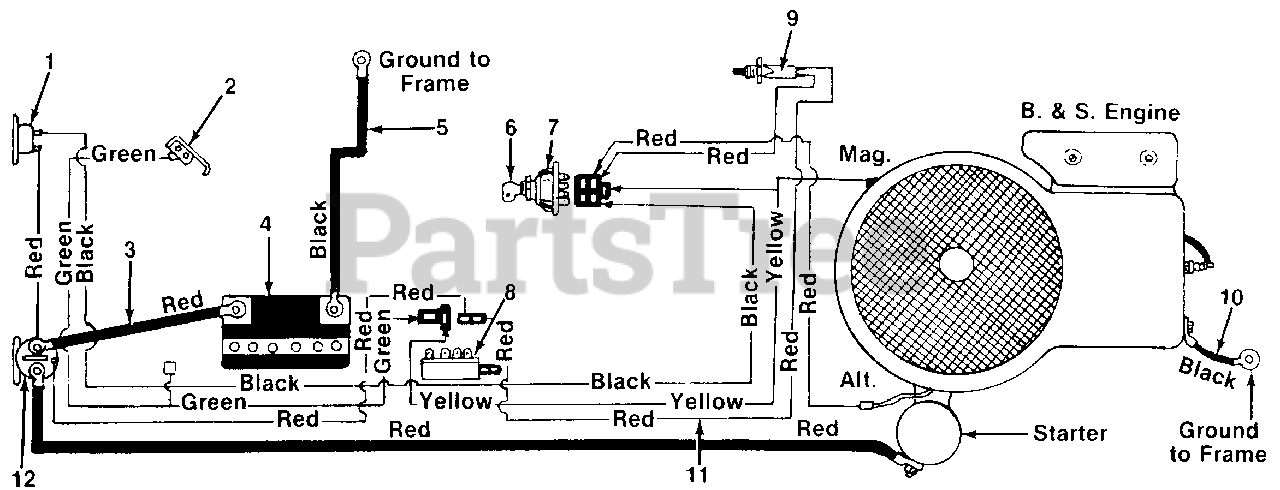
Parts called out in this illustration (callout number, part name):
1	Circuit Breaker
2	Reverse Safety Switch
3	Electric Wire w/Boot
4	12V-Battery
5	Ground Wire 9.0" Lg.
6	Ignition Key
7	Ignition Switch
8	Safety Switch
9	Safety Switch
10	Ground Wire 7.25" Lg.
11	Wire Harness
12	Solenoid
